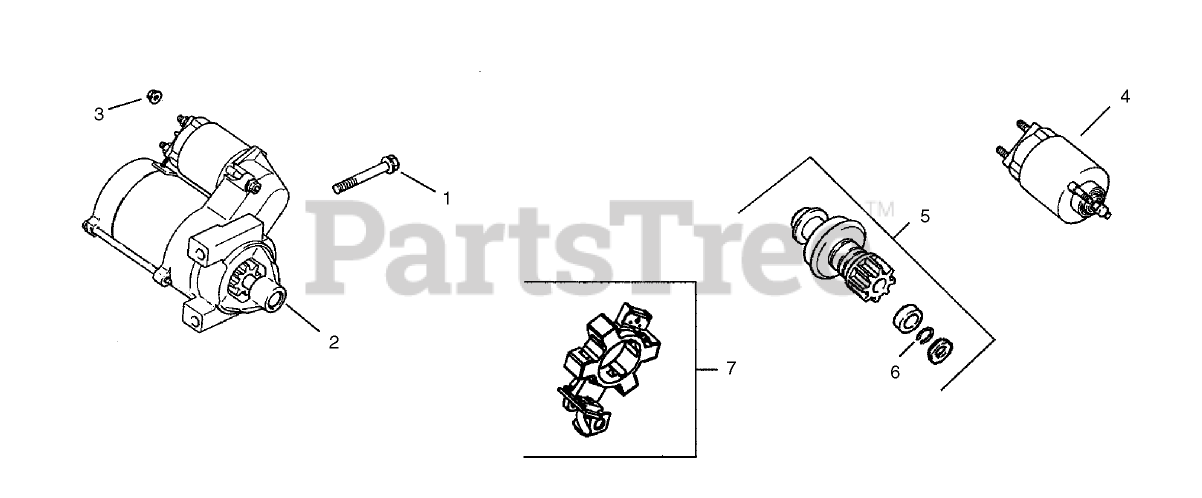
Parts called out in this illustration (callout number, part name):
1	SCREW-FLG (M8X1.25X80)
2	Starter, solenoid shift asm (Includes 4-7)
3	NUT-FLANGE (M8X1.25)
4	Solenoid Kit
5	Kit, pinion drive (Includes 6)
6	RING-RETAINING
7	BRUSH HOLDER KIT
